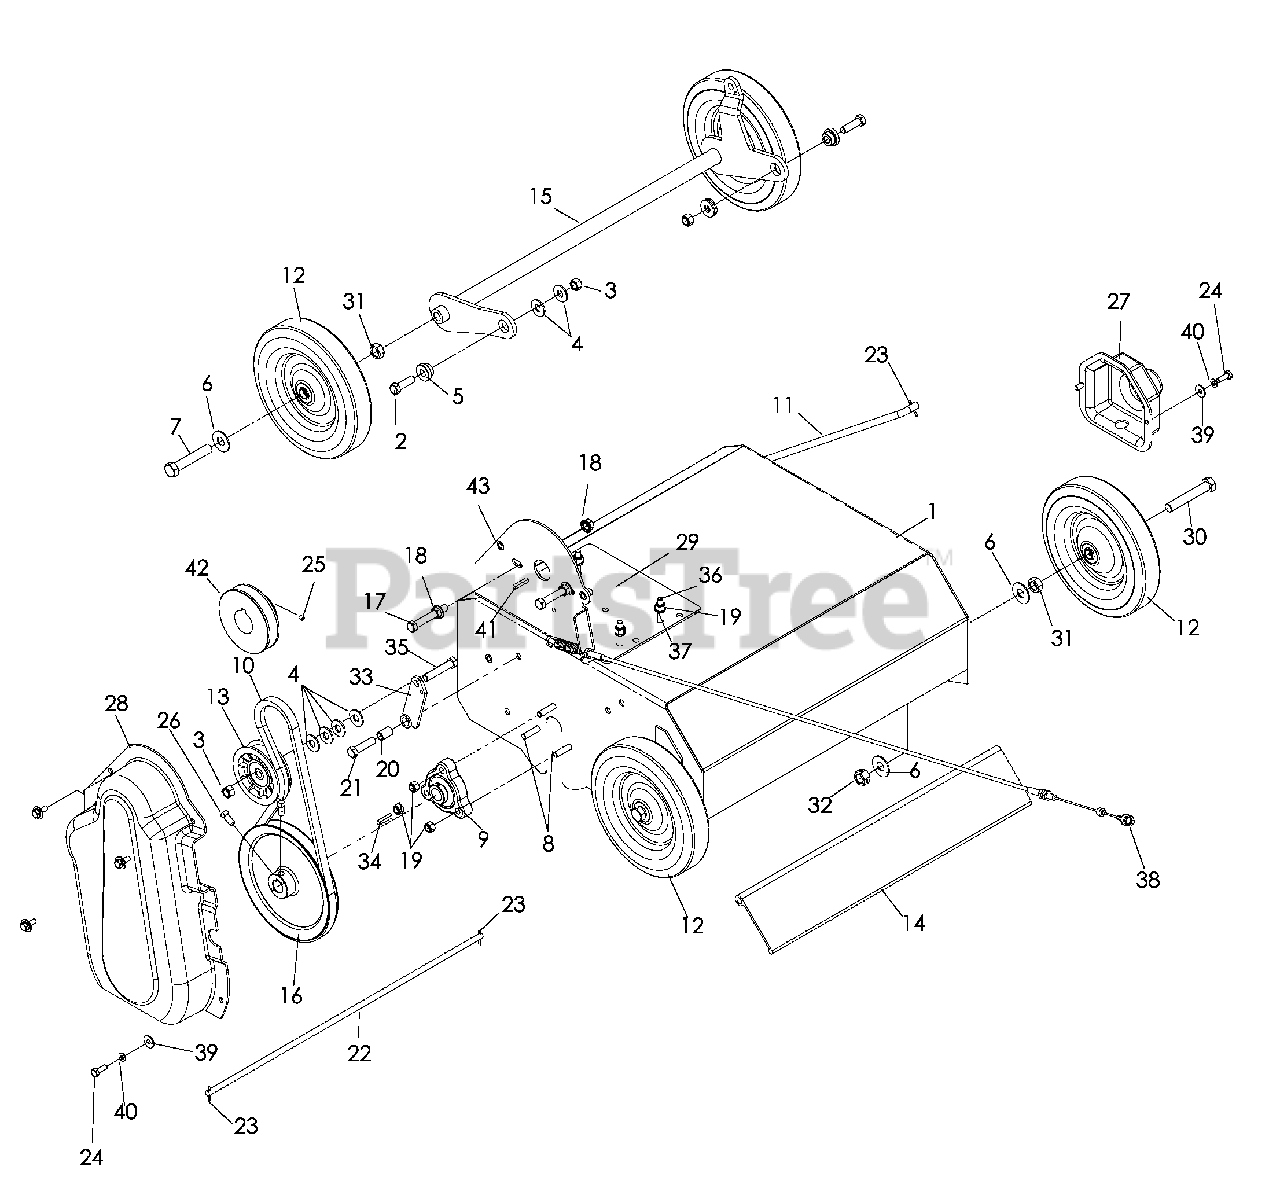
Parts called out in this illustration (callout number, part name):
1	BODY W/DECALS
2	HCS 3/8-16 x 1¼
3	NUT 3/8-16 NYLOC
4	WASHER 3/8 FLAT
6	WASHER ½ FLAT
7	HCS ½-13 x 2¾
8	HCS 5/16-18 x 1¼
9	BEARING, FLANGE
12	WHEEL 8 x 1¾
13	PULLEY, IDLER
15	FRONT AXLE
17	HCS 3/8-16 x 2½
18	NUT 3/8-16 SERRATED
19	NUT 5/16-18 NYLOC
21	HCS 3/8-16 x 1½
23	COTTER PIN
24	HCS ¼-20 x ¾
25	KPSS 5/16-18 x 3/8
26	SCREW-18 x 5/8 SET
27	GUARD, SHAFT
28	GUARD, BELT
29	BACKING PLATE
30	HCS ½-13 x 3
31	NUT ½-13 JAM
32	NUT ½-13 CNTRLK
34	KEY 3/16 x 3/16 x 1
35	HCS 3/8-16 x 2
36	HCS 5/16-18 x 1¾
37	LOCKWASHER 5/16
40	LOCKWASHER ¼
42	PULLEY
43	KNURLED INSERT ¼-20
